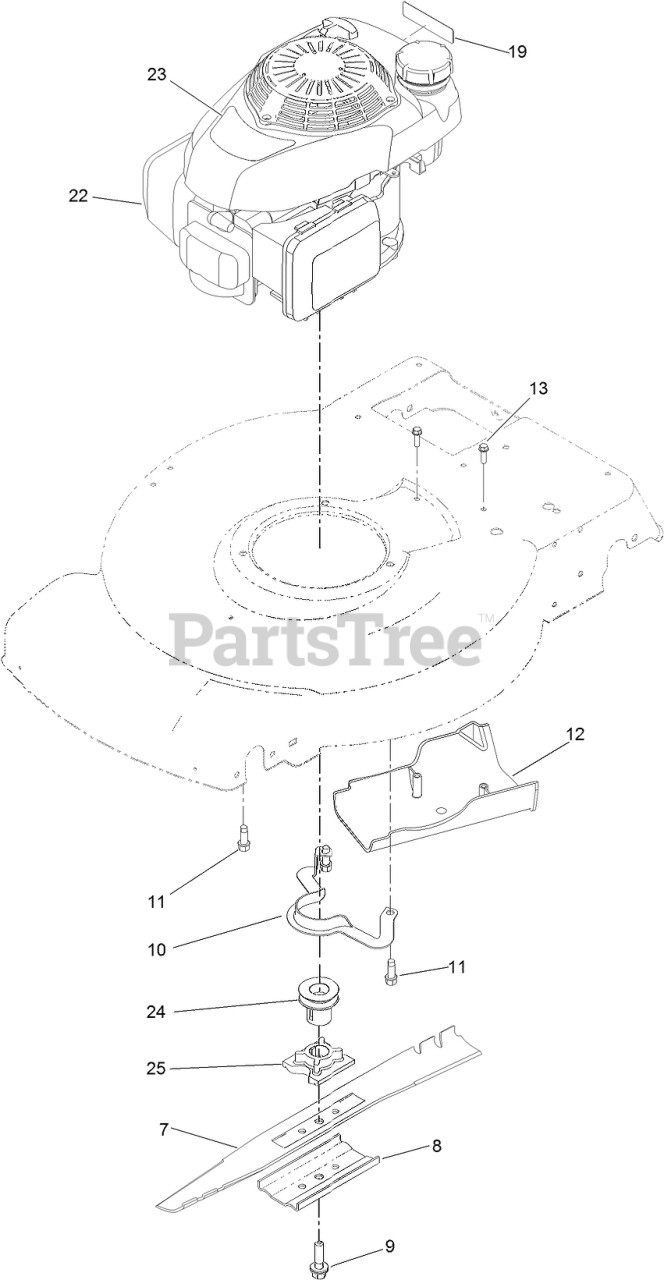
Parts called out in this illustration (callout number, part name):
7	BLADE-22 INCH
8	SUPPORT-BLADE
9	BOLT-BLADE
10	Guide-Belt
11	SCREW-TAPTITE
12	COVER-BELT
13	SCREW-HWH
19	DECAL-ARRESTER, SPARK
23	DECAL-SHROUD, HONDA
24	PULLEY
25	RETAINER-BLADE
